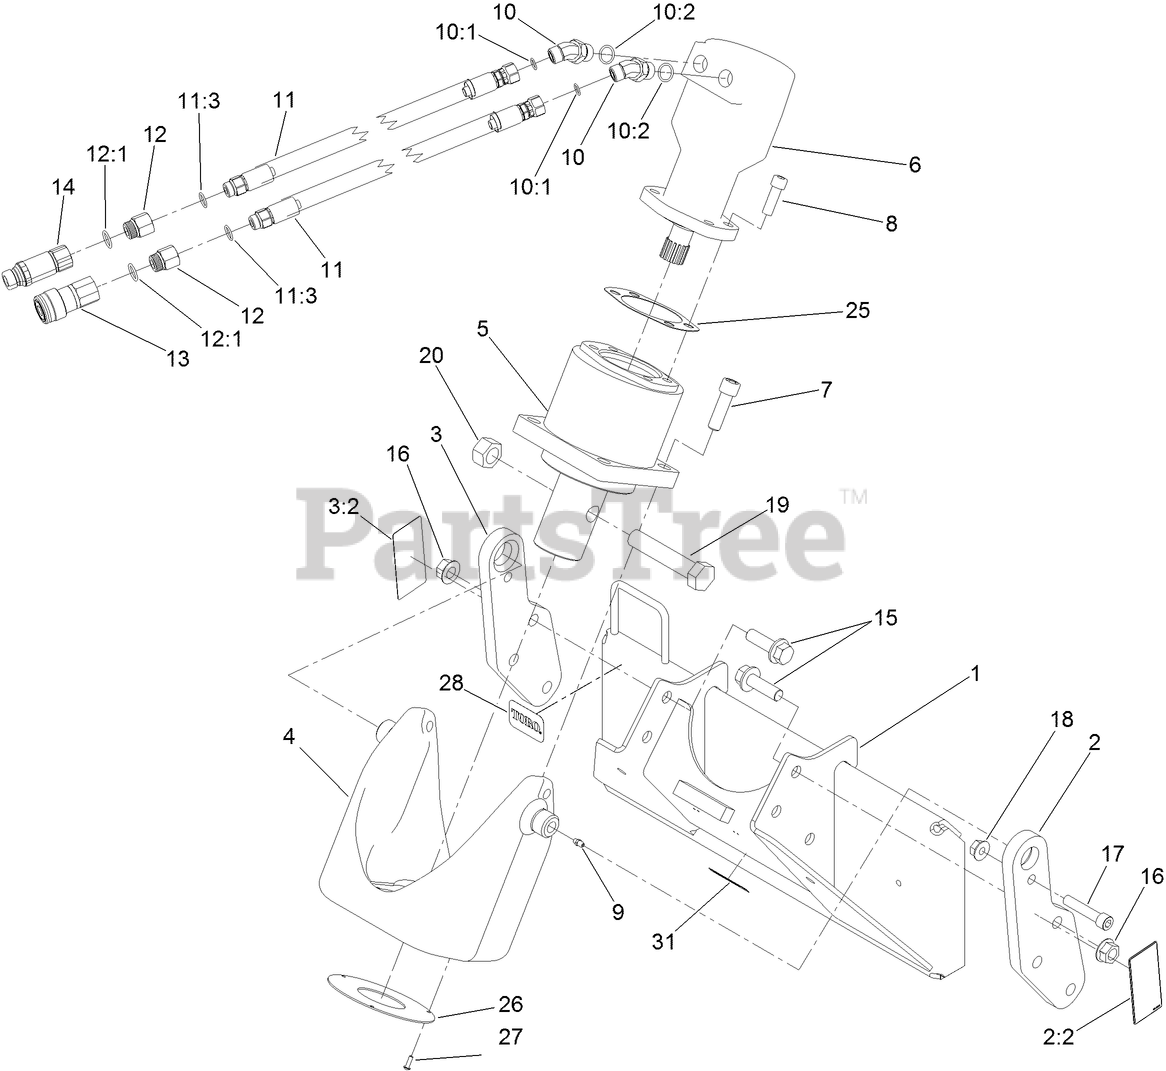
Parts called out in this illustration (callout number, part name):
1	AUGER MOUNT ASM
2	PLATE-PIVOT, LH
2:2	DECAL-DANGER
3	PLATE-PIVOT, RH
3:2	DECAL-DANGER
4	YOKE-AUGERHEAD
5	PLANETARY DRIVE ASM
6	MOTOR-HYD
7	SCREW-HSH
8	SCREW-HSH
9	FITTING-GREASE
10	FITTING-HYD, 45 DEG
10:1	O-RING
10:2	O-RING
11	HYD HOSE ASM
11:3	O-RING
12	ADAPTER-HYD
12:1	O-RING
13	COUPLER-FACE, FLUSH
14	NIPPLE-CONNECT, PRESSURE
16	NUT-FLANGE
17	SCREW-HSH
18	NUT-HHF
19	SCREW
20	NUT-HEX
25	GASKET
26	PLATE-GUARD, SEAL
27	SCREW-HSBH
28	DECAL
31	DECAL-WARNING
